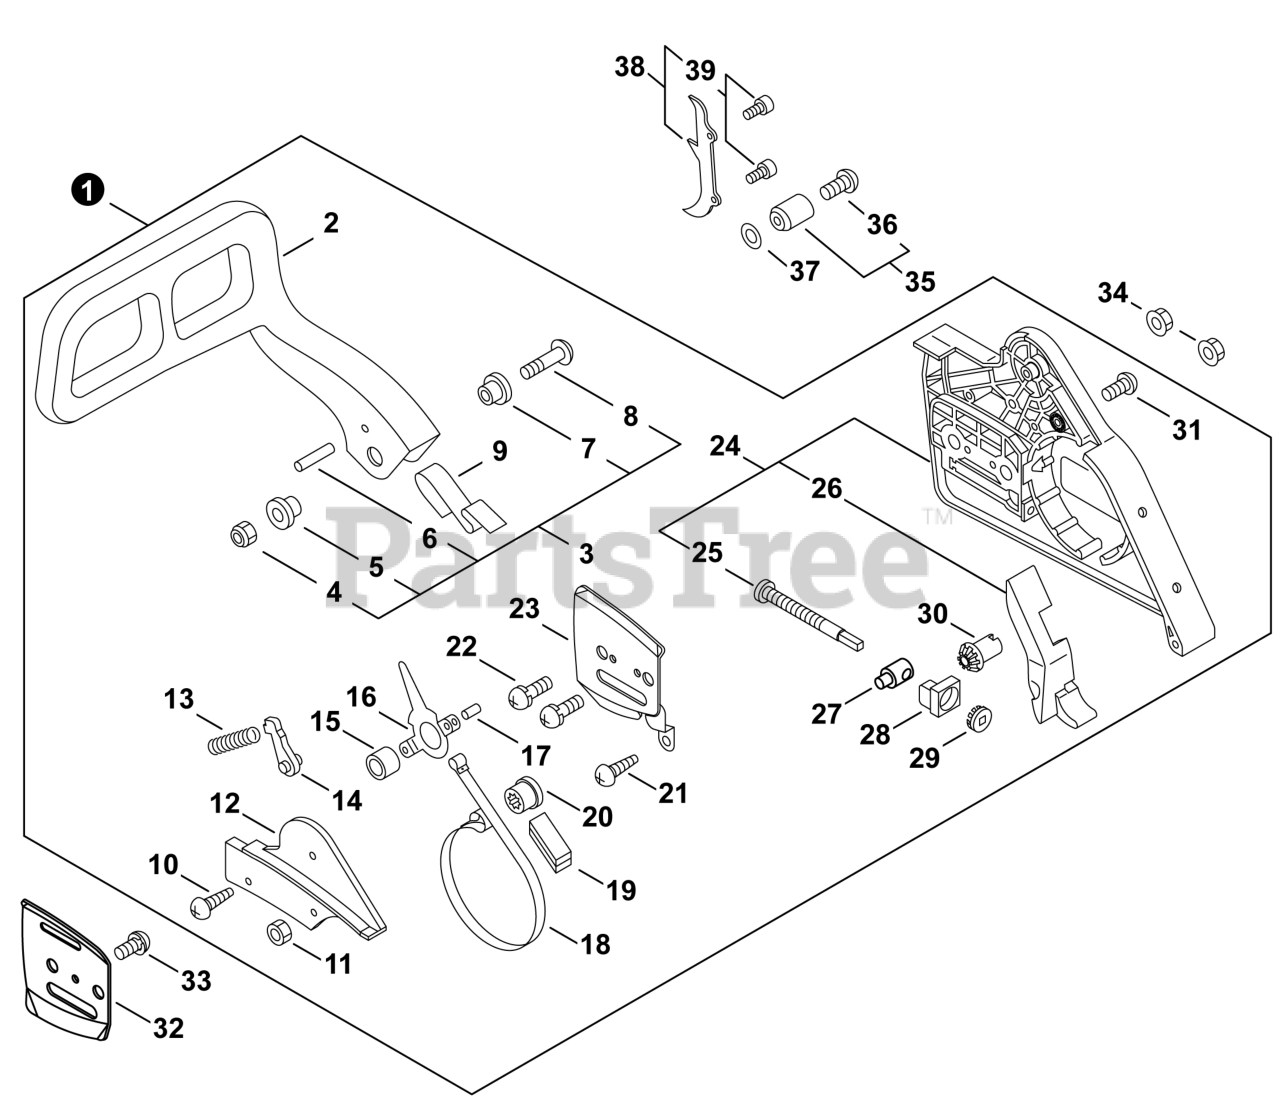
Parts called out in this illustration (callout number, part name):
1	BRAKE ASSY, CHAIN
2	LEVER, BRAKE
3	SCREW KIT
4	NUT, LOCK M5
5	COLLAR 5.3×10×13×L5
6	PIN 3.5×26
7	COLLAR 5
8	SCREW 5×35
9	SPRING, FLAT
10	SCREW 4×12
11	NUT 3 MM
12	COVER, BRAKE
13	SPRING, BRAKE
14	STOPPER, BRAKE
15	SPACER 8×12×9
16	LEVER, BRAKE
17	PIN, SPRING 4×8.8
18	BAND, BRAKE
19	SEAL, BRAKE
20	ADJUSTER, BRAKE
21	SCREW 4×10
22	SCREW 3×6
23	PLATE, GUIDE - OUTER
24	GUARD KIT, SPROCKET
25	SCREW, CHAIN TENSION
26	CUSHION
27	TENSIONER, CHAIN
28	COLLAR 8
29	GEAR, BEVEL
30	GEAR, BEVEL
31	SCREW 3×18
32	PLATE, GUIDE - INNER
33	SCREW 4×8
34	NUT, FLANGE M8×1.25
35	CHAIN CATCHER KIT
36	SCREW 5×18
37	WASHER, FLAT 5.5×10×0.8
38	SPIKE KIT, BUMPER
39	BOLT 5×12
